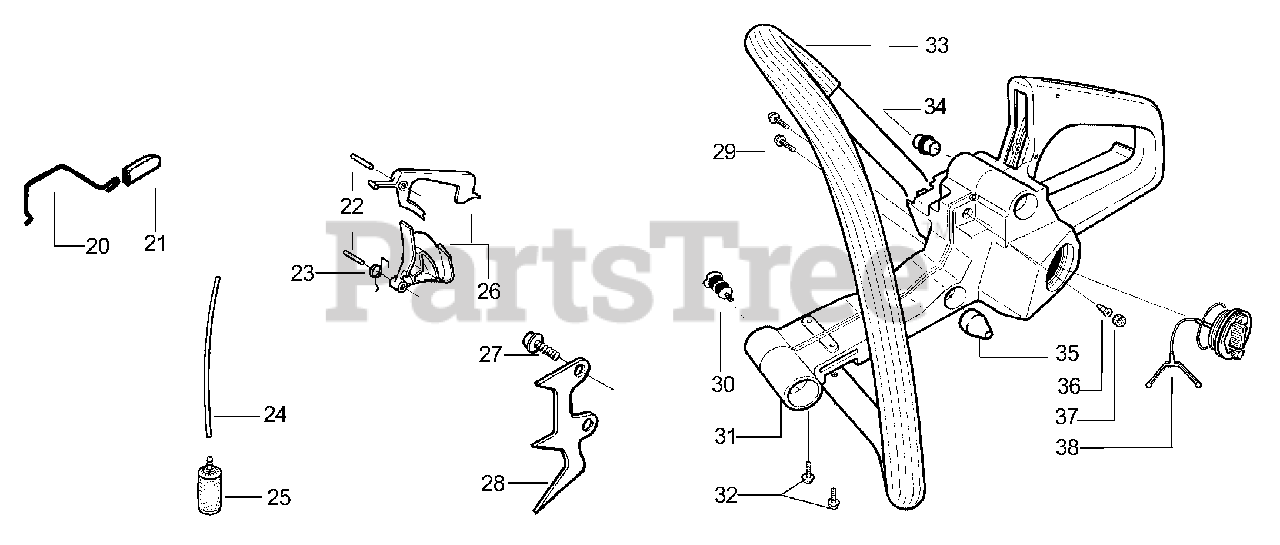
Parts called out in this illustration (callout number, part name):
20	Wire - Throttle
21	Cap - Wire
24	Kit - Fuel line
25	Assy. Fuel Pickup
26	Kit - Throttle Trigger
28	Assy. Spike
31	Assy. -Tank/Handle
33	Handle-Front
34	Isolator - Limiter
35	Isolator Bumper
36	Valve - Check
37	Plug - Vent
38	Assy. Fuel Cap
